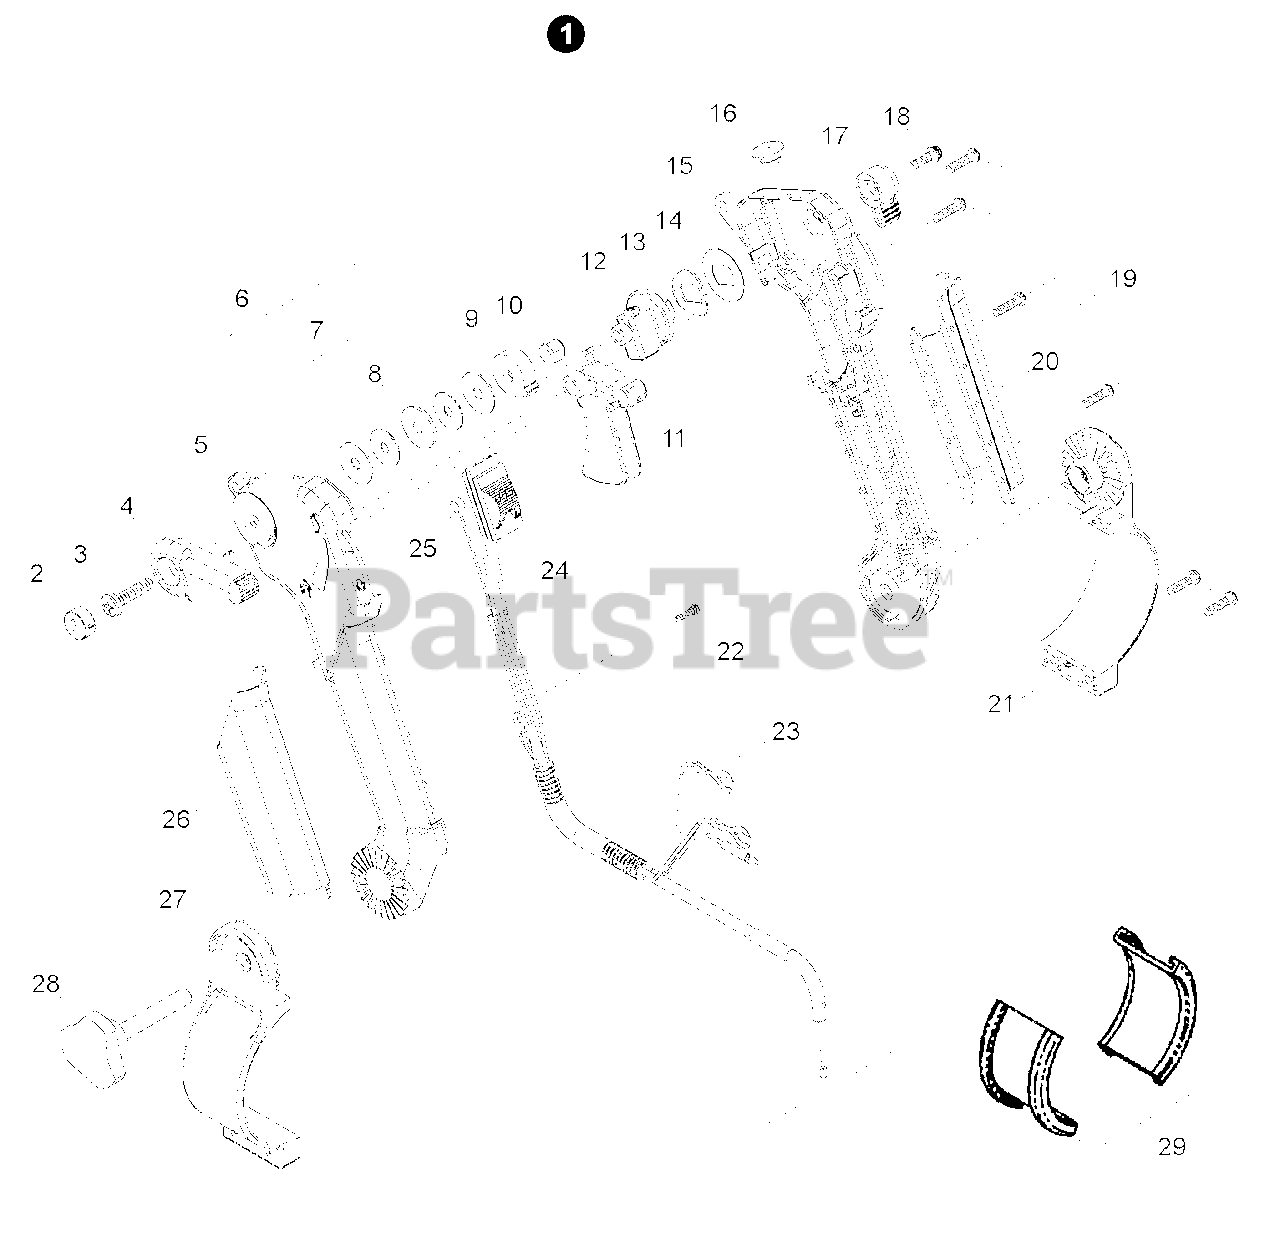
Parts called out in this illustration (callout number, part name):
1	THROTTLE CONTROL ASSY
2	CAP, BOLT
3	BOLT M6×25
4	CONTROL, THROTTLE
5	CONTROL HANDLE - LEFT
6	WASHER M6
7	WASHER, SPRING
8	WASHER M6
9	LEVER, THROTTLE
10	NUT, NYLON M6
11	TRIGGER, THROTTLE
12	LIMITER ASSY, THROTTLE
13	WASHER, WAVE
14	WASHER
15	CONTROL HANDLE - RIGHT
16	PLUG, THROTTLE LIMITER
17	LEVER, THROTTLE LIMITER
18	SCREW M4×16
19	SCREW M4×16
20	GRIP, RIGHT
21	BRACKET, RIGHT
22	SCREW M3×8
23	CABLE ASSY, CONTROL
24	SWITCH, ON-OFF
25	CABLE, THROTTLE
26	GRIP, LEFT
27	BRACKET, LEFT
28	KNOB, SCREW
29	SPACER
